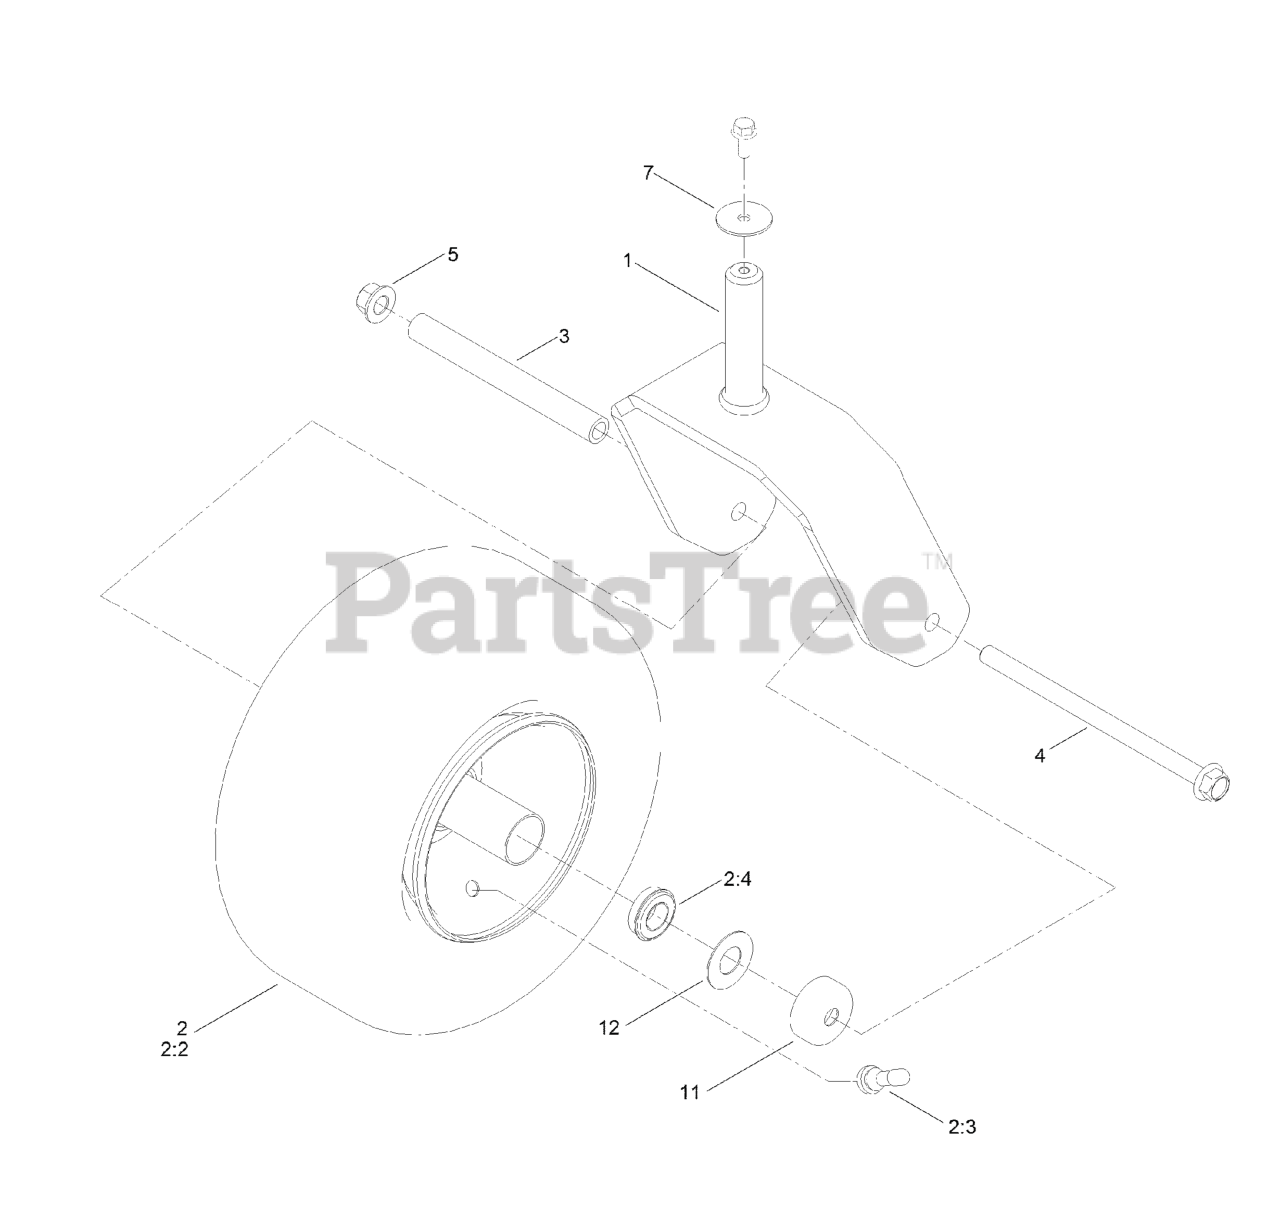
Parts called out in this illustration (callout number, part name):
2	TIRE AND WHEEL ASM
2:3	Stem-Valve
2:4	BEARING
3	SPANNER-WHEEL
4	SCREW-HHF
5	Nut-Lock 1/2-13
7	WASHER-FLAT
11	GUARD-SEAL
